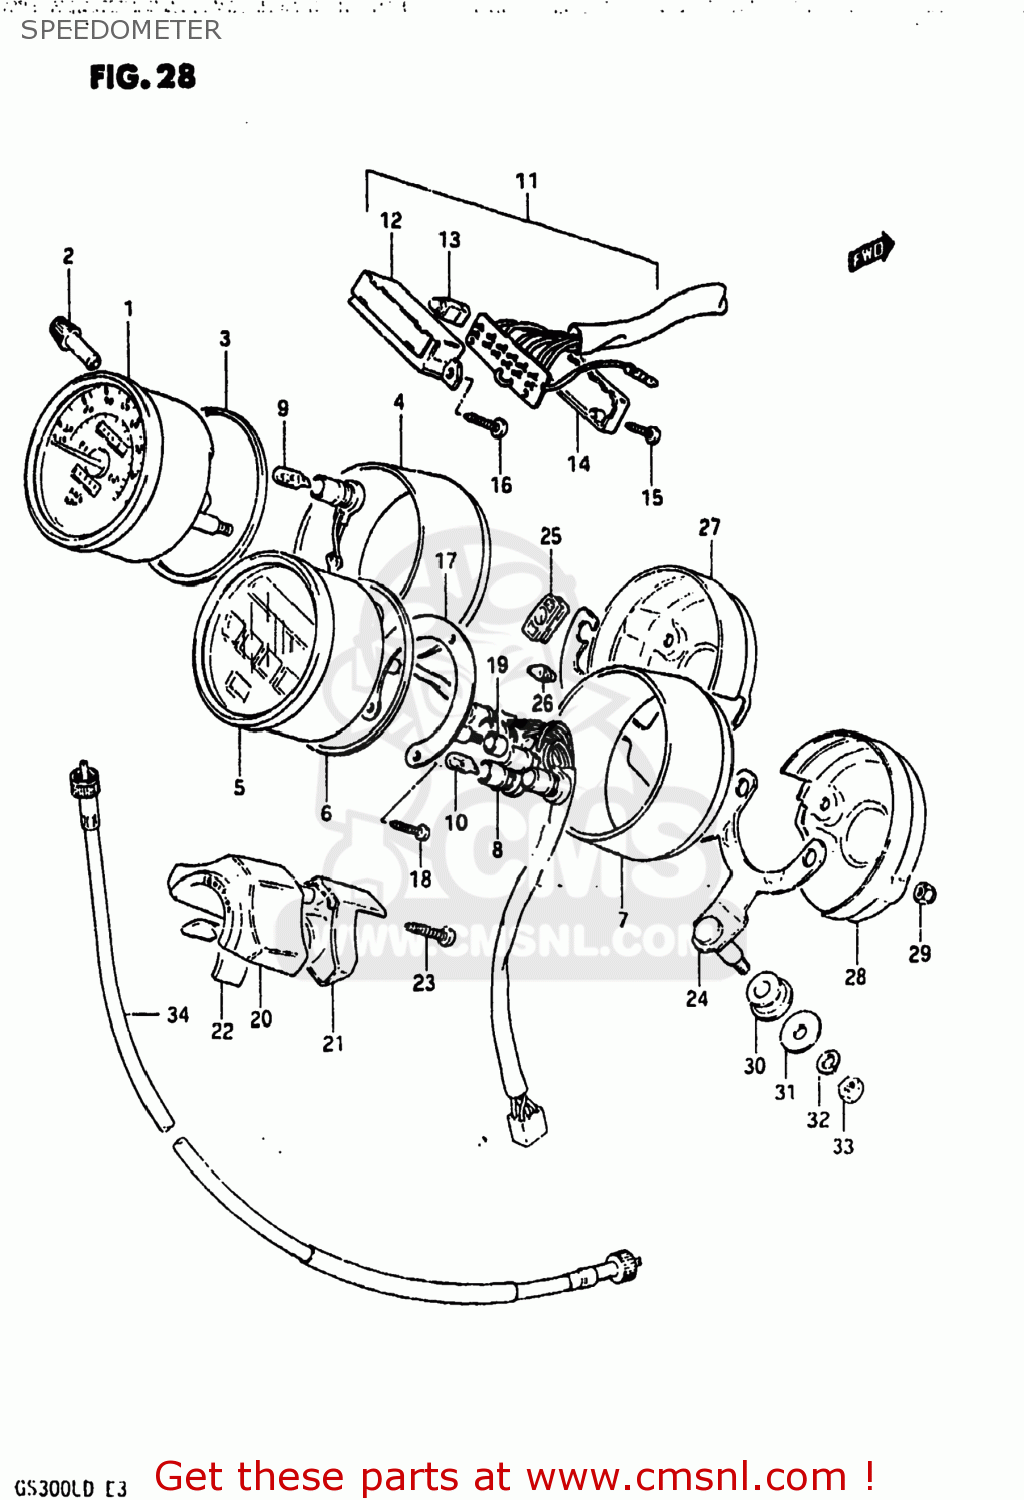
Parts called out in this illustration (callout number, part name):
1	SPEEDOMETER ASSEMBLY
2	KNOB
3	CUSHION
4	COVER,SPEEDOMETER
5	BOX ASSEMBLY,PILOT LAMP
6	CUSHION
7	COVER,TACHOMETER
8	SOCKET
9	BULB(12V1.7W,T10,WB121)
10	BULB(12V3.4W,T10)
11	INDICATOR ASSEMBLY,GEAR POSITION
12	CASE,GEAR INDICATOR
13	BULB(14V1.12W)
14	COVER,LWR
15	SCREW,GEAR INDICATOR
16	SCREW,INDICATOR
17	CUSHION,METER
18	SCREW
19	CAP
21	COVER,IGNITION SWITCH
22	SEAL,IGNITION SWITCH
24	BRACKET,METER
25	CUSHION,METER
26	CUSHION
27	ORNAMENT,SPEEDOMETER
28	COVER,INDICATOR,UNDER
29	NUT
30	CUSHION,METER BRACKET
31	WASHER (8.5X20X1.6)
32	LOCK WASHER
33	NUT
34	CABLE ASSEMBLY,SPEEDOMETER
